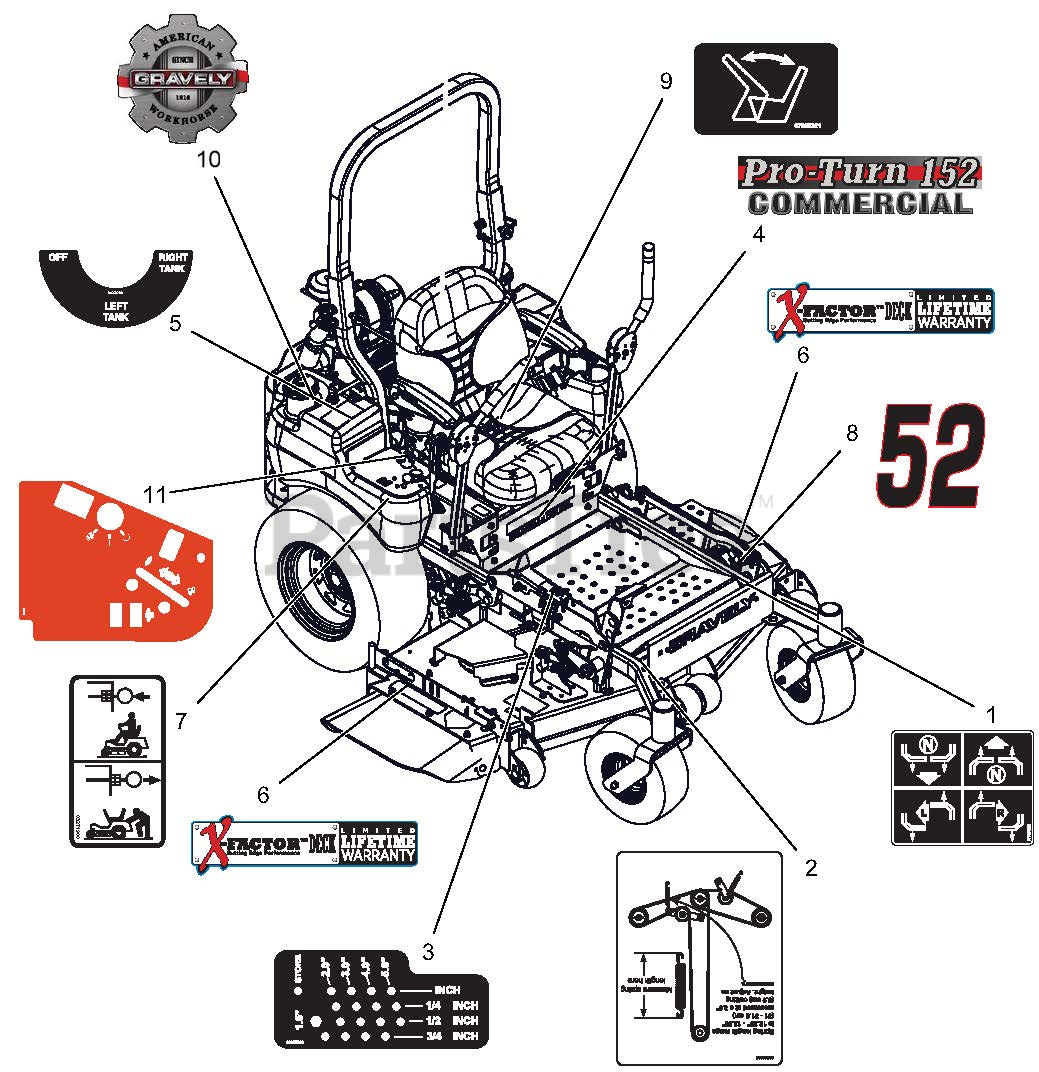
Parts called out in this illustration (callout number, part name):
1	DECAL, INSTRUCTIONAL - STEERING
2	DECAL, BELT ROUTING
3	DECAL, HEIGHT OF CUT
4	DECAL, PRO-TURN 152
5	DECAL, FUEL VALVE
6	DECAL, X-FACTOR DECK
7	DECAL, TRANSMISSION DISCONNECT
8	DECAL, 52"
9	DECAL, SEAT RELEASE
10	DECAL, GRAVELY HERITAGE-LARGE
11	PANEL, PT100 CONTROL
